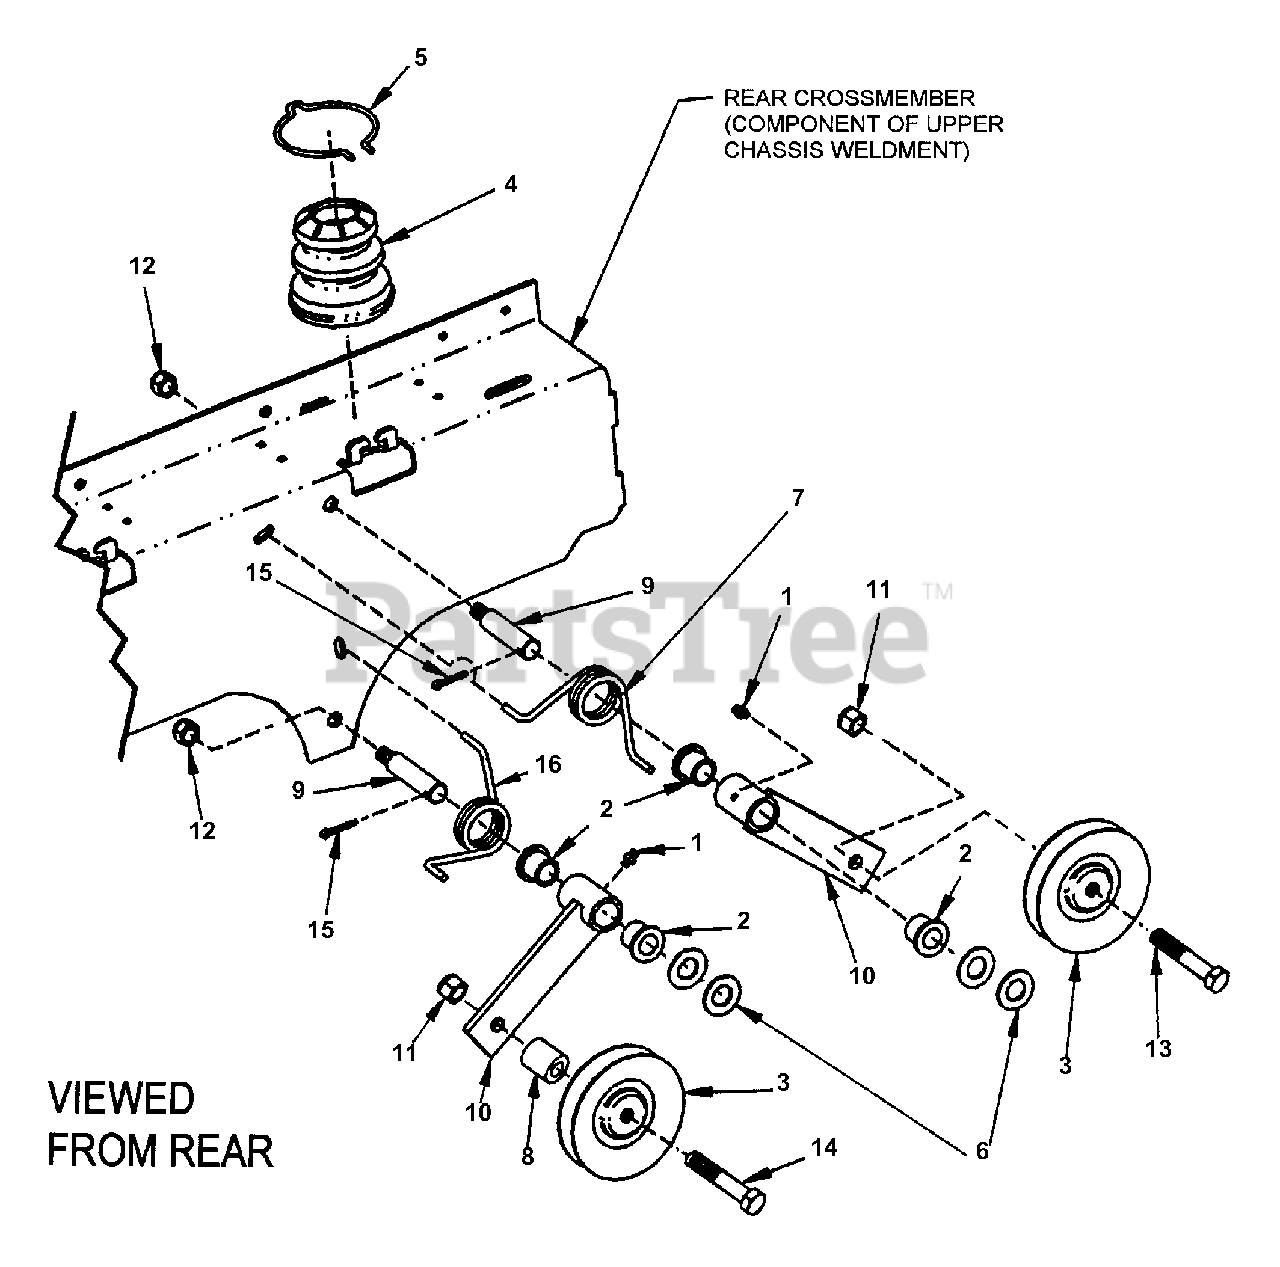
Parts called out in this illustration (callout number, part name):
1	FITTING, 3/16 Lube
2	BUSHING, 9/16 I.D., 3/4" O.D.
3	PULLEY, Idler 3.48 O.D.
4	COVER, Spring (Rubber)
5	CLIP, Seat Cushion
6	WASHER, 9/16 Flat (Type B)
7	SPRING, Torsion
8	SPACER, 3/8 I.D. 5/8 O.D. x 5/8" Long
9	PIN, 3/8-24
10	IDLER ARM (Weldment)
11	NUT, 3/8-16 HEX NYLON LOCK
12	NUT, 3/8-24 Hex Nyloc
13	SCREW, 3/8-16 x 1-3/4" Hex Head Cap, Grade 5
14	SCREW, 3/8-16 x 2-1/4" Hex Head Cap, Grade 5
15	COTTER PIN, 1/8 x 3/4"
16	SPRING, Torsion
